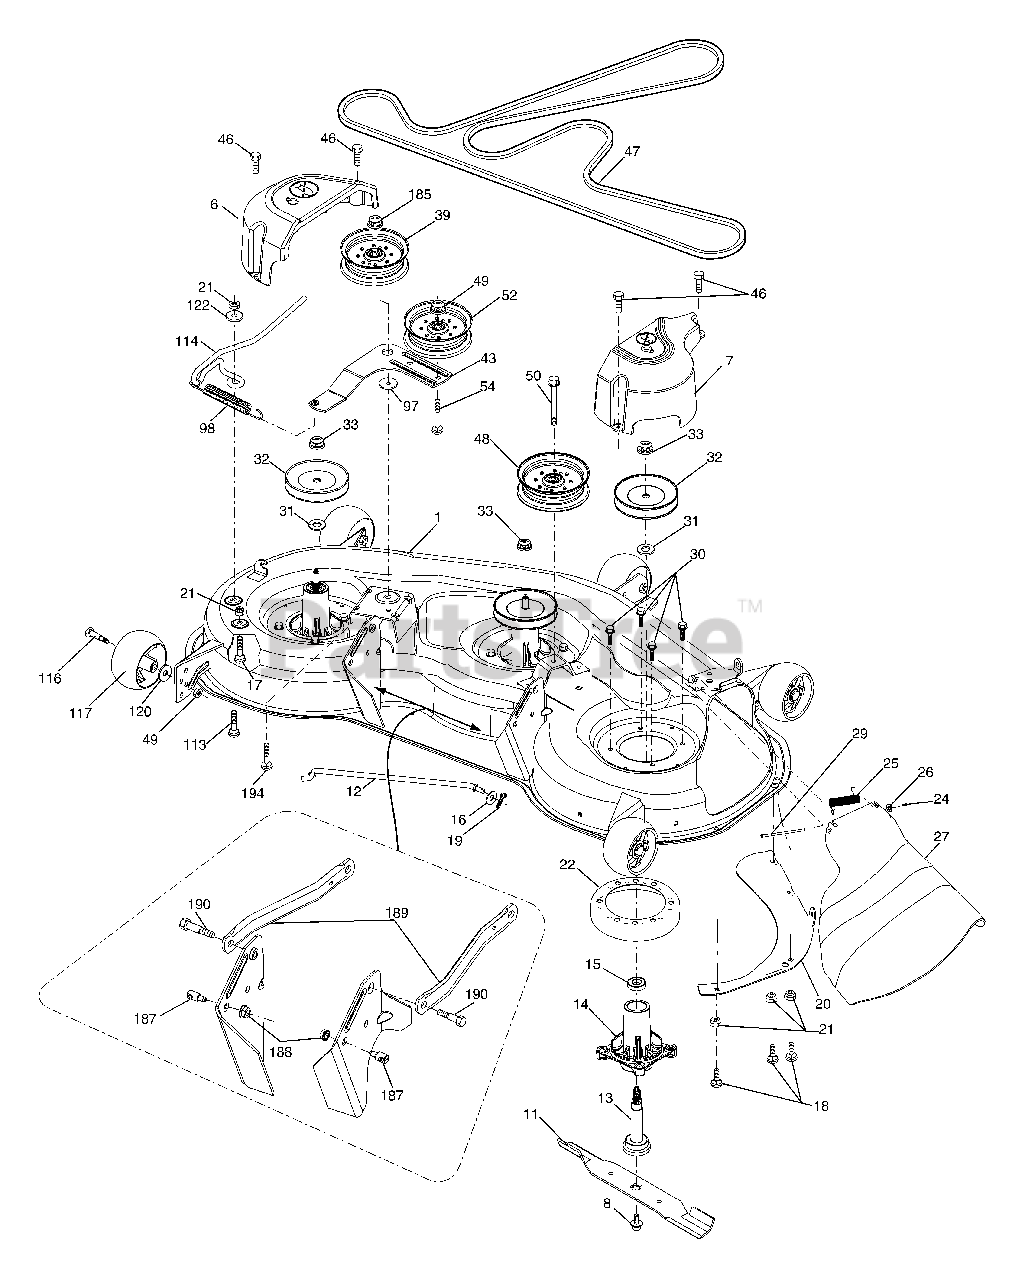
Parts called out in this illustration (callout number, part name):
1	Deck Weldment Mower
6	Cover Mandrel LH
7	Cover Mandrel RH
8	Bolt 7/16 Asm. Blade
11	Blade High Lift
12	Rod Anti Sway
12	Blade Mulching
13	Shaft Asm. w/Lower Bearing
14	Housing, Mandrel
15	Bearing, Ball, Mandrel
16	Washer 3/8
18	Bolt Rd Hd 5/16-18 unc x 5/8
19	Pin Cotter 5/16 Bowtie
20	Baffle Vortex
21	Nut, Crownlock 5/16-18 unc
22	Stripper Mandrel
24	Cap Sleeve
25	Spring, Torsion
27	Deflector Shield
29	Rod, Hinge
30	Screw, Thdroll Washer Head
31	Washer, Spacer Mower Vented
32	Pulley, Mandrel
33	Nut, Flg. Top Lock
39	Pulley, Idler, Stationary LH
43	Arm, Idler
46	Screw, Thdroll. 1/4-20 x 5/8
47	Belt Deck Drive
48	Pulley Idler
49	Nut, Lock Flg. 3/8-16 unc
50	Bolt Carr SH 3/8-16 x 1-1/2 Gr.5
52	Pulley Idler Clutching
54	Screw 3/8-16 x 2-1/4
97	Washer Hardened
98	Spring Drive
113	Bolt Rdhd Sqnk 5/16-18 x 3/4
114	Rod Tension Relief
116	Bolt, Shoulder
117	Gauge Wheel
120	Washer 13/32 x 1-1/4 x 12 Ga.
122	Bushing Tension Relief
185	Nut Lock Flange 7/16-14 Gr. 5
187	Stud Fastener w/"D" Anti-Rotation
188	Nut Lock Hex Flange 5/16-18
189	Arm Susp. Mower Rear
190	Bolt Shoulder
194	Bolt Carr Sqnk 7/16-24 x 2
